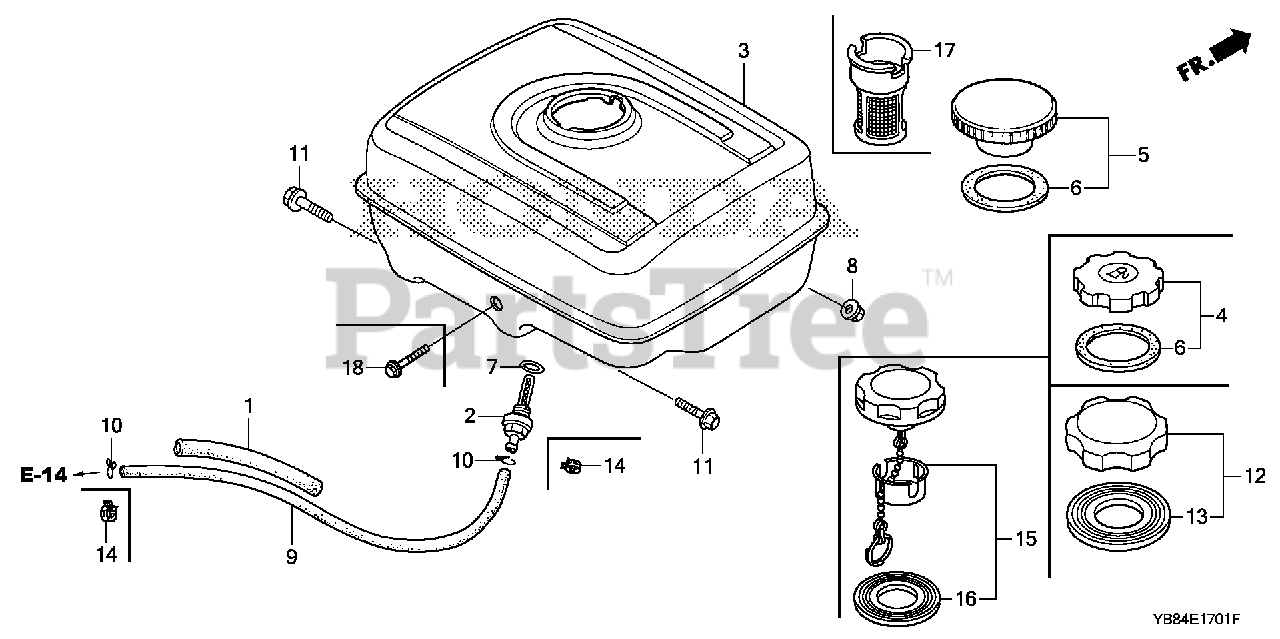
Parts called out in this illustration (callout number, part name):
1	RUBBER, SUPPORTER (107MM)
2	JOINT, FUEL TANK
3	TANK, FUEL *R280* (POWER RED)
5	CAP, FUEL FILLER (BLACK)
6	GASKET, FUEL FILLER CAP (39X58X3)
7	O-RING (13.5X1.5) (ARAI)
7	O-RING (14MM) (NOK)
8	NUT, FLANGE (8MM)
9	BULK HOSE, FUEL (4.5X3000) (4.5X222)
10	CLIP, TUBE (B8)
11	BOLT, FLANGE (8X25)
